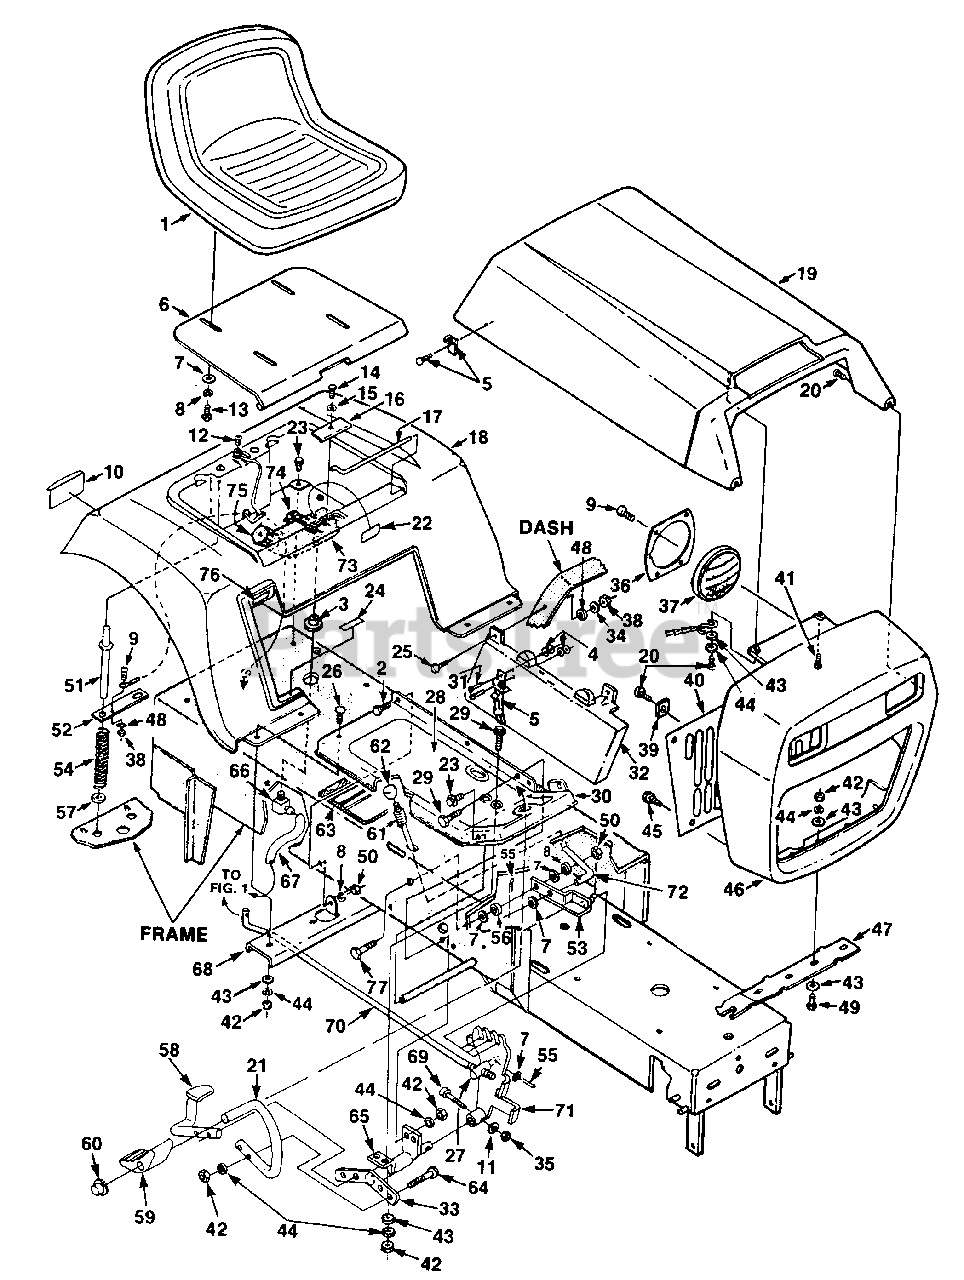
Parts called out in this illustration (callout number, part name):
2	SCREW- Hex hd. (5/16-18 x 3/4")
4	WASHER- Flat
6	PAN- Seat
7	WASHER- Flat (5/16")
8	WASHER- Lock Hvy. (5/16")
9	SCREW- (#10-24 x 3/8")
10	REFLECTOR
11	WASHER- Thrust
12	SCREW- (#10 x 1/2")
13	SCREW- (5/16-18 x 5/8")
14	SCREW- (1/4-20 x 3/4")
15	WASHER- Lock (1/4")
16	BRACKET- Rod. Ret.
17	ROD- Hinge
20	SCREW- (1/4-14 x 1")
21	FORWARD ARM
22	DECAL- Fill Level
24	DECAL- Lo-Lift Position
25	SCREW- (#10-24 x 1/2")
26	BOLT- (1/4-20 x 1")
28	PAD- Footboard (L.H.)
29	SCREW- (1/4-20 x 5/8")
30	FOOTBOARD (L.H.)
32	PANEL- L.H. Side
33	PLATE & SHAFT
34	WASHER- Flat (#10)
35	NUT (#10-24)
36	RETAINER- Headlight
37	HEADLIGHT
38	NUT- (#10-24)
39	CLIP- Grill Top
41	SCREW- (1/4-14 x 3/4")
42	NUT- Hex (1/4-20)
43	WASHER- Plain (1/4")
44	WASHER- Lock (1/4")
45	SCREW- (1/4-14 x 1/2")
47	GRILLE HINGE
48	LOCKWASHER (#10)
49	SCREW- (1/4-20 x 7/8")
50	NUT- Hex (5/16-18)
51	PIN- Seat Support
52	CONTACT- Interlock
53	CONTROL ARM
54	SPRING- Compression
55	PIN- Cotter (3/32 x 3/4")
57	WASHER- Insulating
58	ARM- Reverse
59	PEDAL- Rubber
60	NUT- (5/8")
63	DECAL- Operation Warning
64	SCREW- (1/4-20 x 1/4")
65	TUBE & SUPPORT
66	CONNECTOR
67	TUBING- Reservoir (7.25)
68	BRACKET- Footboard
69	SCREW- Socket (#10-24 x 1/3/4")
72	ROD- Cruise Control
73	RESERVOIR
74	STRAP
76	DECAL- High Lift Position
77	SCREW- Hex Hd. Cap (5/16-18 x 1")
